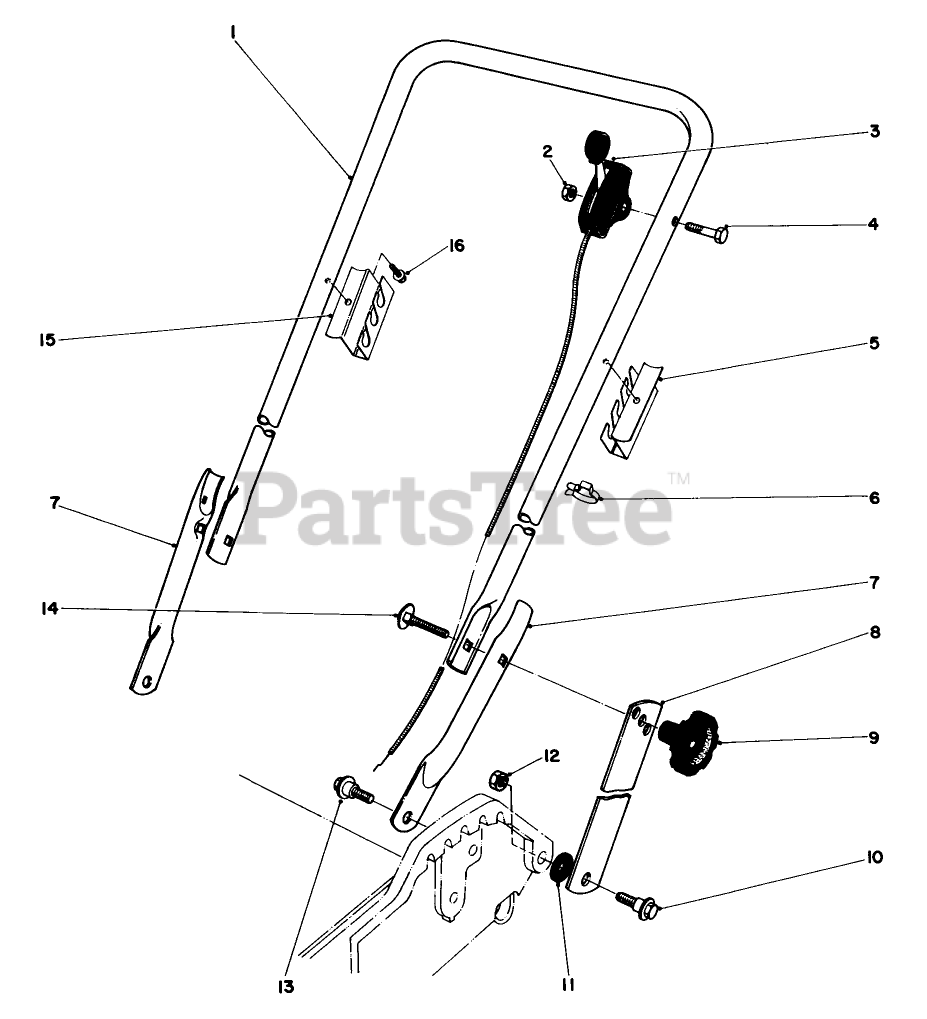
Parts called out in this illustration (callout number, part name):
3	SERVICE THROTTLE CONTRO
4	SCREW-HH
5	SUPPORT BAG LH
6	BOWDEN CLIP
10	SCREW-SHOULDER
11	SPACER
12	NUT-LOCK, NI
13	SCREW-SHOULDER
16	SCREW-HWHTF
